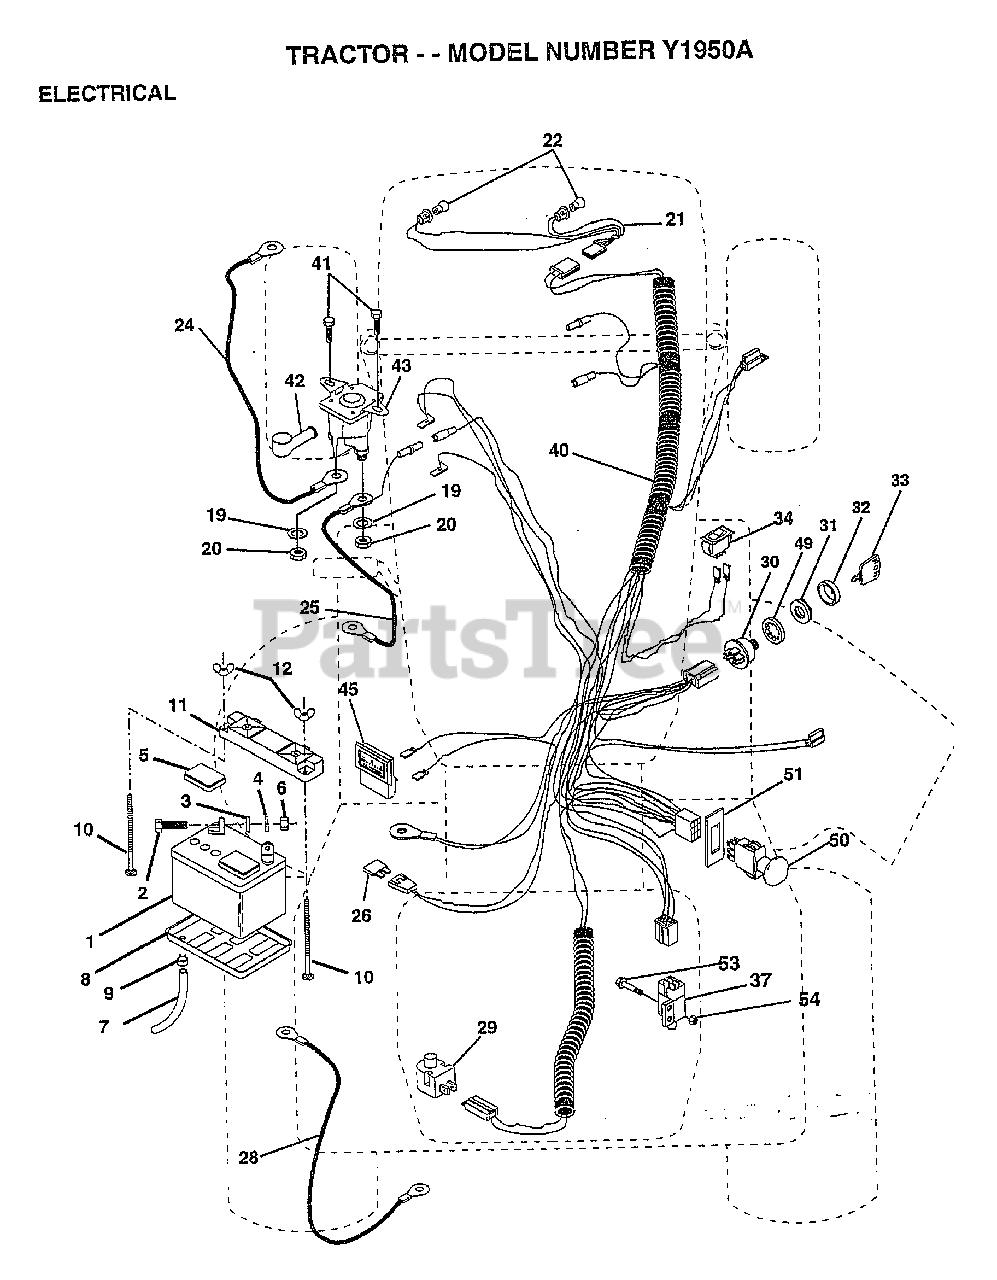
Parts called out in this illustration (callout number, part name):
2	BOLT LT
3	LOCKWASHER
4	WASHER
5	"CAP,BATTERY "
7	"DRAIN TU T, BATT"
8	"TRAY T, BATTERY"
9	HOSE CLAMP T
20	NUT
21	"HARNESS,LIGHT SOC"
22	HEADLAMP BULB
24	"CABLE T, BATTERY"
25	CABLE.6GA.12.5.
26	FUSE HYT
28	CABLE T
29	SWITCH SEAT
32	COVER KEY SWITCH
33	KEY MLD GEN DELTA
34	SWITCH LT
37	SWITCH INTERLOCKT
40	HARNESS.IGN.VGT.
41	SCREW
45	AMMETER
49	LOCKWASHER
51	RING RETAIN PTO
53	SCREW
54	"NUT,KEPS"
